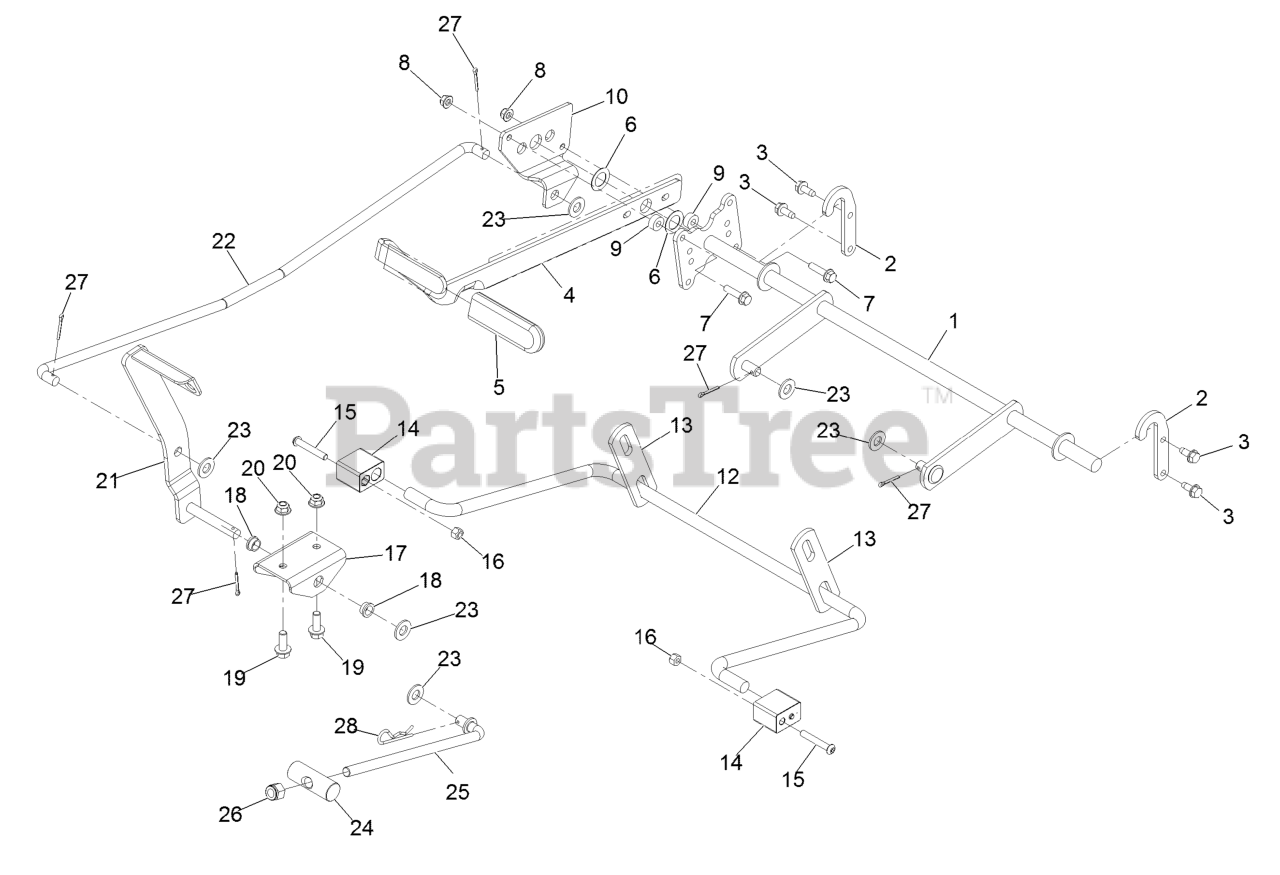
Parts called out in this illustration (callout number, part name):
1	Lift-Deck, Wide
2	Bracket-Lift
3	Screw-HWH 5/16-18 X 3/4 Tf
4	Handle-Deck Lift
5	Grip-Lever
6	Washer-Thrust
7	Screw-HH Flg 5/16-18 X 1 1/4
8	Nut-Nyloc 5/16-18 Flg
10	Plate-Footlift
12	Arm-Lift, Rear (Wide)
13	Link-Lift
14	Block-Pivot
15	Screw-Button Head 5/16-18 X 2.00
16	Nut-Nyloc 5/16-18
17	Bracket-Footlift
18	Bushing-Flange
19	Screw HHF 3/8-16 X 1
20	Nut-Nyloc 3/8-16 Flg
21	Pedal ASM
22	Rod-Footlift
23	Washer-1/2 SAE
24	Pin-Pivot
25	Rod-Mount, Deck
26	Nut-Nyloc 1/2-20
27	Pin-Cotter 1/8 X 1
28	Hairpin-Cotter
